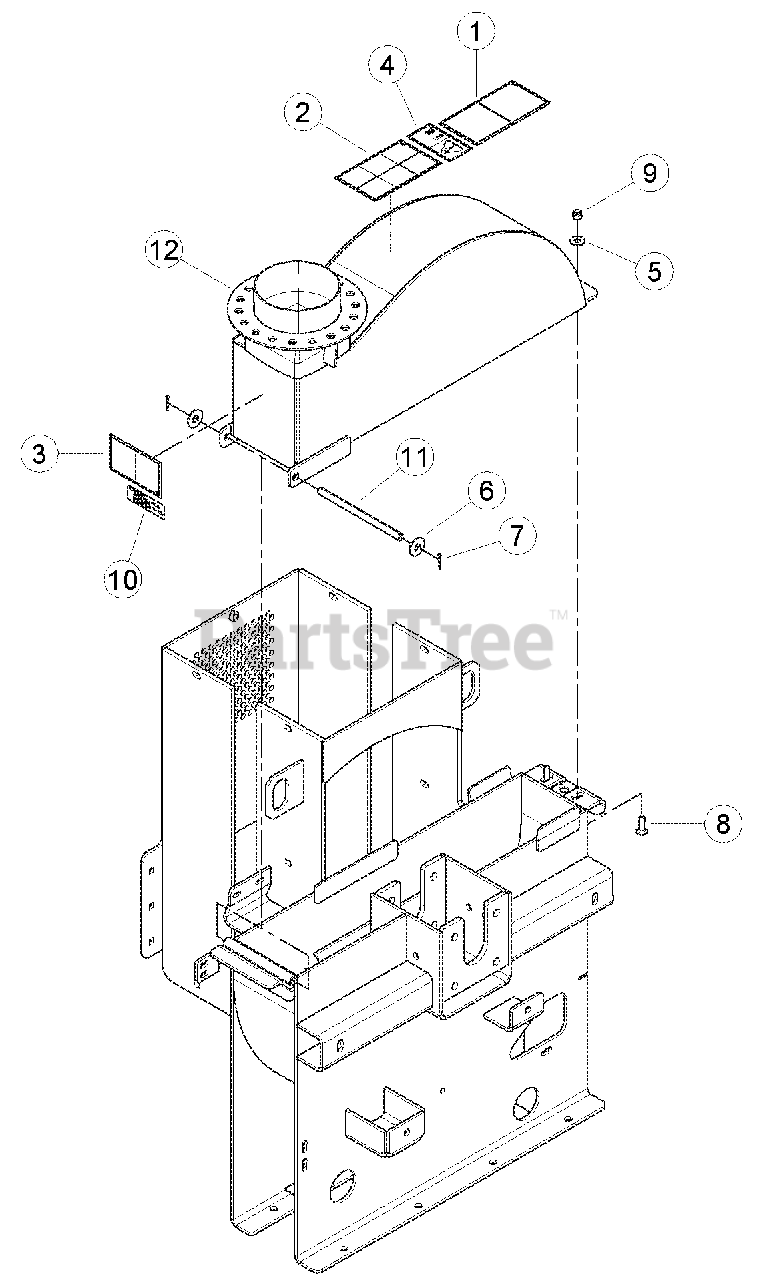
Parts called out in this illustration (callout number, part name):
1	DECAL, KNIFE ACCESS ISO
2	DECAL, OPERATING INSTRUCTIONS ISO
3	DECAL, DISCHARGE ISO
4	DECAL, MAINTENANCE ISO
5	WASHER, 3/8 FLAT ZP
6	WASHER, 1/2 FLAT ZP
7	PIN, 1/8 X 1.00 COTTER ZP
8	BOLT, 3/8 X 1-1/4 CRG GR5 NC ZP
9	NUT, 3/8 NE NYLOCK ZP
10	DECAL, ATLANTIC BRIDGE LTD INFO (CE COMPLIANT ONLY)
11	SHAFT, CHIPPER TOP PIVOT
12	WELDMENT, CHIPPER TOP
